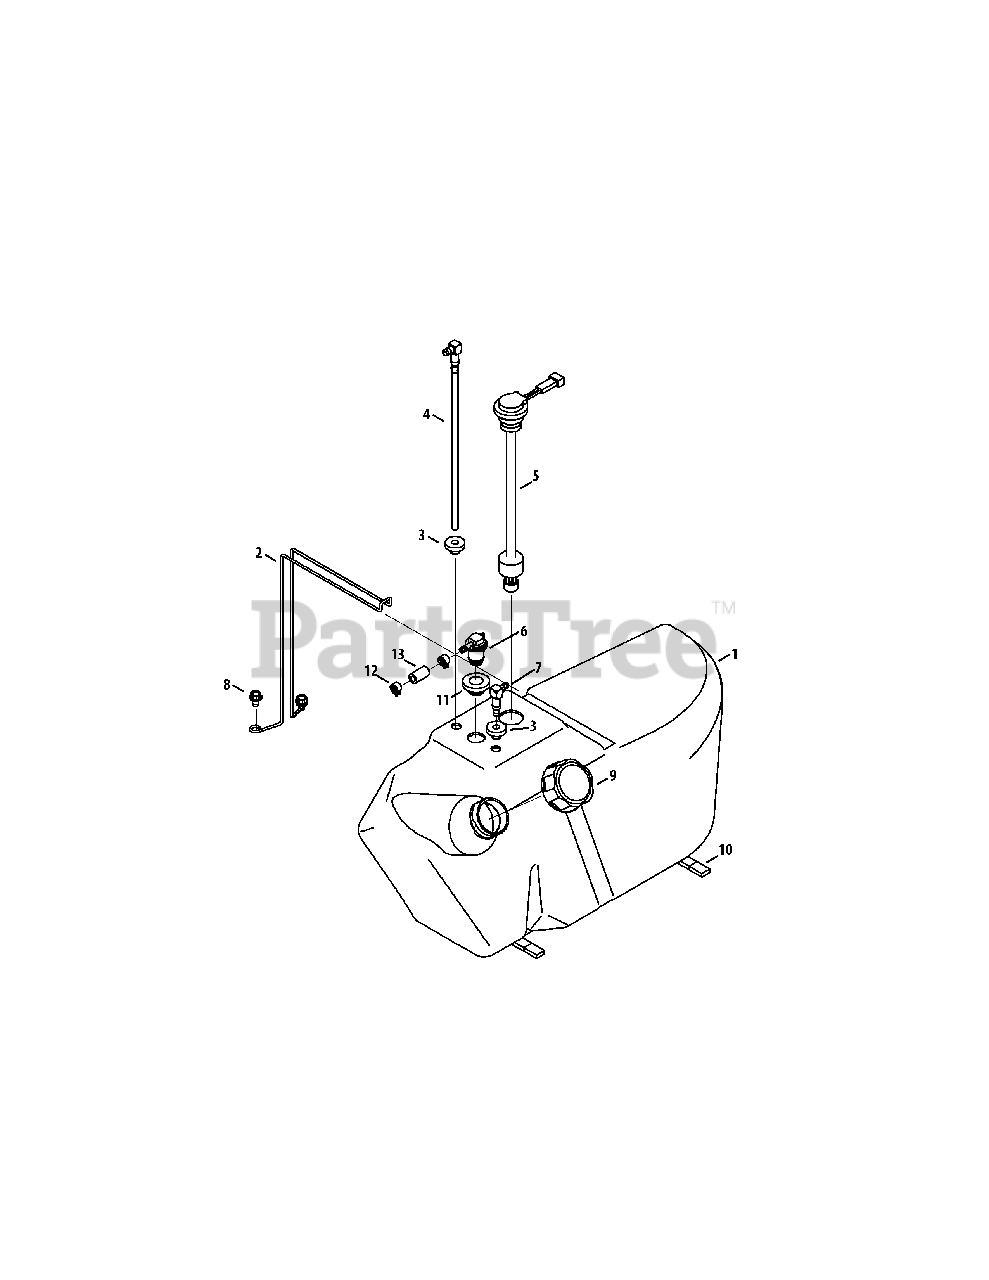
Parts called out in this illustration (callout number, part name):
1	Tank assembly, Fuel
2	Wire, tank, fuel
3	Bush, Tank, Gas
4	Fitting, Fuel, Pickup
5	Sensor, Fuel, Low
6	Fitting, Fuel, Vent
7	Fitting, Fuel, Pickup
8	Screw, 5/16-18 x .500
8	Screw, 5/16-18 x .75
9	Cap, Fuel
10	Tape, .75 Wide x.25 Thk Foam
11	Bush, Tank, Vent
12	Clamp, Hose, .490 Dia.
13	Fuel Line, 5/16 Id
